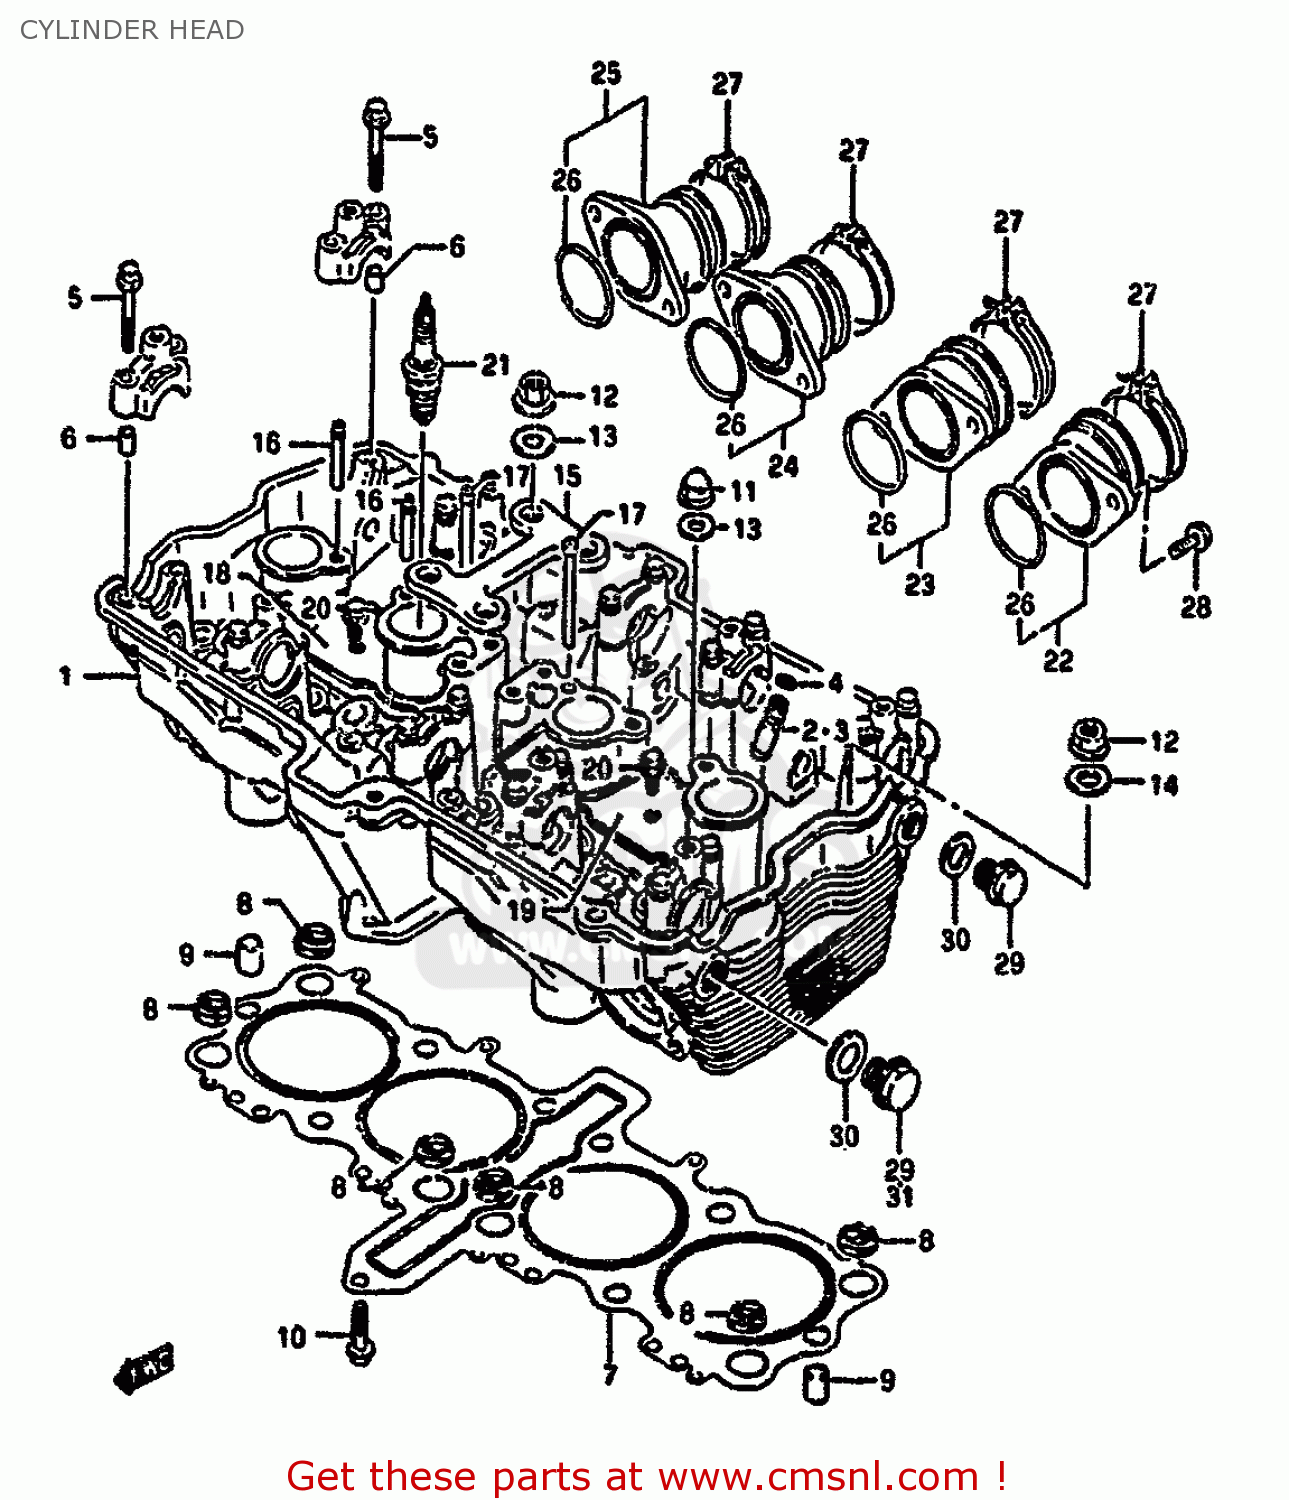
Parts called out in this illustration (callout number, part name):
1	HEAD ASSY,CYLINDER
2	GUIDE,VALVE
3	GUIDE,VALVE
4	RING,SNAP
5	BOLT(6X39)
6	PIN(6.2X8X11)
7	GASKET,CYLINDER HEAD (NAS)
8	O-RING,HEAD GASKET
9	PIN
10	BOLT
11	NUT
12	NUT
13	GASKET(10.2X20X2).3 (NAS)
14	WASHER (10.5X22X2.3)
15	PLATE,HEAD REINFORCEMENT
16	PIPE,OIL NO.1
17	PIPE,OIL NO.3
18	PLATE,OIL PIPE,R
19	PLATE,OIL PIPE,L
20	BOLT
21	PLUG,SPARK(JR9B)
22	PIPE,INTAKE NO.1
23	PIPE,INTAKE NO.2
24	PIPE,INTAKE NO.3
25	PIPE,INTAKE NO.4
26	O RING(D:2.4,ID:39.7)
27	CLAMP
28	SCREW
29	PLUG
30	GASKET(14X19.2X2) (NAS)
31	PLUG
